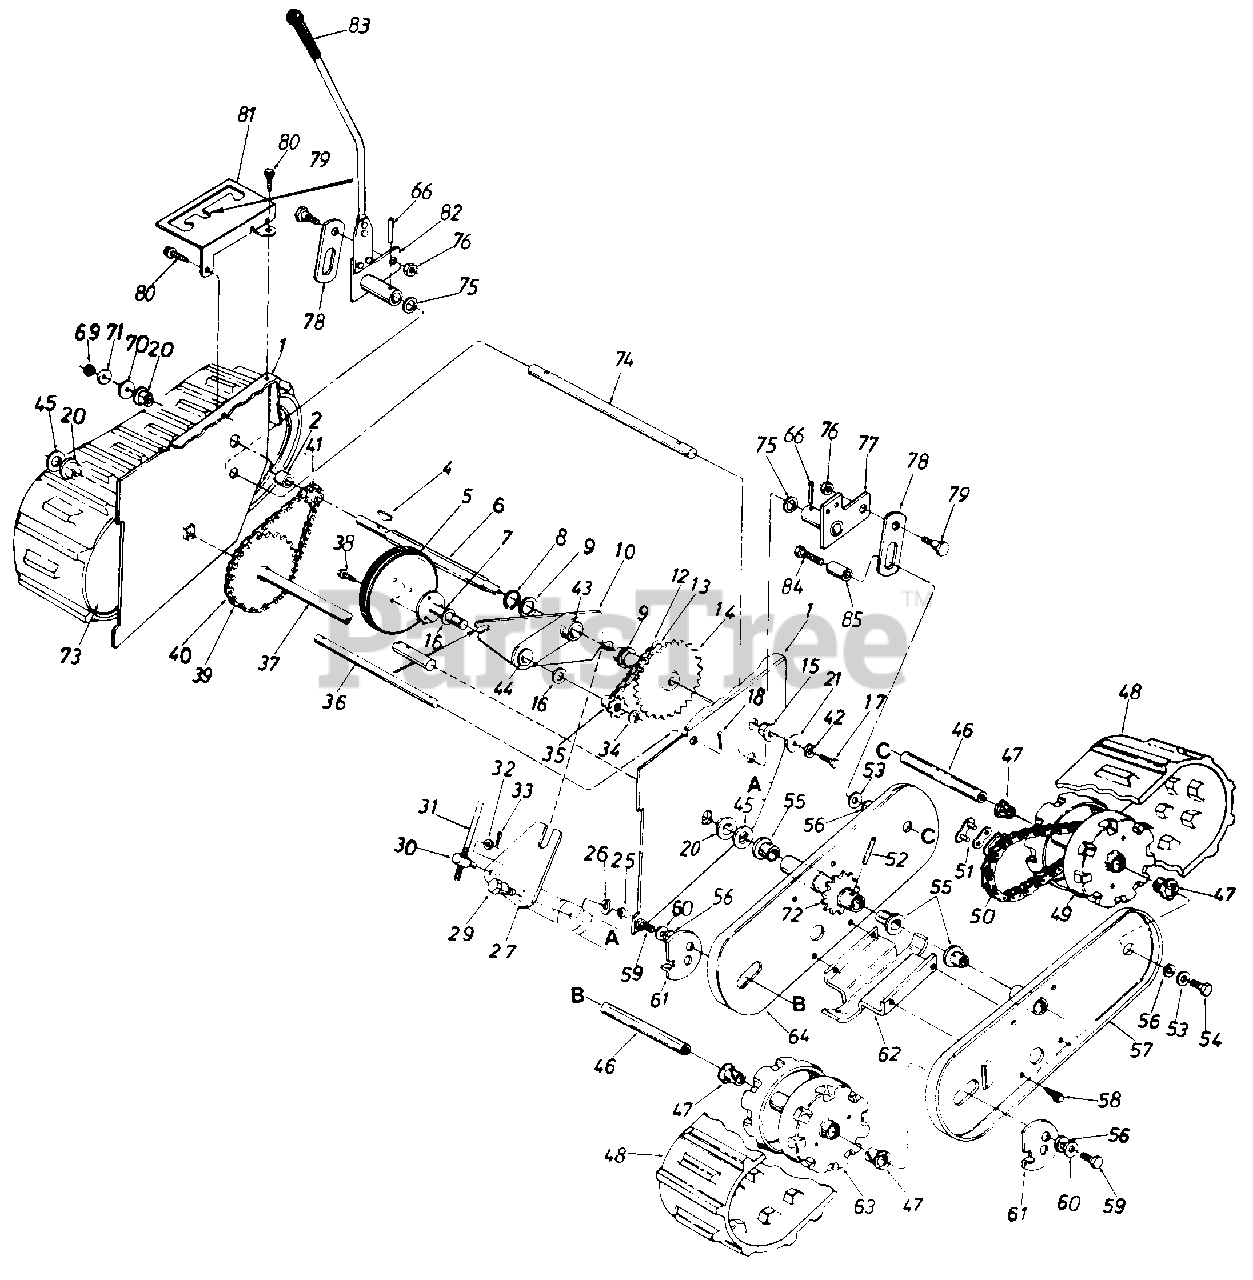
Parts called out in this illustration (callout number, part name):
1	Frame Ass'y.
2	Spacer .50" I.D. x .75" O.D. x .78" Lg.
4	#4 Hi-Pro Key 3/32 x 518" Dia.
5	Friction Wheel Ass'y.
6	Hex Shaft
7	Friction Wheel Mounting Plate Ass'y.
8	Snap Ring 1.00" Dia. Shaft
9	Fl-Wash. 1.00" x 1.63" O.D. x.03
10	Sliding Bracket Ass'y.
12	#41 Chain 1/2" Pitch x 35 Links
13	Master Link for #41 Chain
14	32 Teeth Sprocket Ass'y.
15	Hex Flange Brg. .630" I.D.
16	Fl-Wash. .62" I.D. x 1.00" O.D. x .06
17	Hex Lock Bolt 5/16-18 x .62" Lg.
18	Cotter Pin 3/32" Dia. x .75" Lg.
20	Hex Flange Brg. .751" I.D.
21	Fl-Wash. .34" I.D. x 1.12" O.D. x 125
25	Hex Jam Nut 3/8-16 Thd.
26	L-Wash. 318" I.D.
27	Shifting Linkage Bracket
29	Shld. Bolt 625" Dia. x 170" Lg.
30	Adjustment Ferrule
31	Shifting Rod 5/16" Dia. x 32.50" Lg.
32	Fl-Wash. .34" I.D. x .64" O.D. x .06
33	Cotter Pin 3/32" Dia. x .75" Lg.
34	Snap Ring .562" Dia. Shaft
35	Sprocket 7 Teeth x 50" Pitch
36	Shaft .50" Dia. x 9.50" Lg.
37	32 Teeth Wheel Shaft Ass'y.
38	Hex Wash. Hd. Self-Tap Scr. 5/16-24 x .50" Lg.
39	#420 Chain 1/2" Pitch x 39 Links
40	Master Link for #420 Chain
41	8 Teeth Center Sprocket
42	L-Wash. 5/16" I.D.
43	Plastic Bearing
44	Bronze Bearing
45	Fl-Wash. 76" I.D x 1.49 O.D.
46	Wheel Shaft 5/8 x 4.25" Lg.
47	Flange Brg. .632" I.D.
48	Snow Track 5" x 48"
49	Drive Wheel Ass'y.
50	Chain #420 x 50 Pitch x 37 Links
51	Master Link #420
52	Spring Pin Spir. 1/4" Dia. x 1.50" Lg.
53	Bell-Wash. 345" I.D. x .88" O.D.
54	Hex Bolt 5/16-24 x .62" Lg.
55	Flange Brg. .757" I.D.
56	Fl-Wash. .510" I.D. x 1.0" O.D.
57	Outer Plate Ass'y.-L.H.
58	Hex Wash. S-Tap Scr 1/4-20 X .50" Lg.
59	Hex Bolt 5/16-24 x .62" Lg.
60	Bell-Wash. .345" I.D. x .88" O.D.
61	Track Adjuster
62	Skid Shoe
63	Idler Wheel Ass'y.
64	Inner Plate Ass'y.-L.H.
66	Spring Pin 1/4" x 1.25" Lg.
69	Hex Ins. L-Nut 1/2-20 Thd.
70	Fl-Wash. .53 I.D. x 1.25 O.D. x .10
71	Bell-Wash. .50 I.D. x 1.0 O.D. x .075
72	17T Sprocket Hub Ass'y.
73	Inner Plate Ass'y.-R.H.
74	Track Lock Axle
75	Fl-Wash. 5/8 I.D. x 1" O.D.
76	Hex L-Nut 3/8-16 Thd.
77	Pivot Arm Ass'y.-L.H.
78	Slotted Link
79	Shld. Bolt .625" Dia. x .217
80	Hex Wash. AB-Tap Scr. 5/16 x .75" Lg
81	Position Selector Plate
82	Track Lock Handle Ass'y.
84	Hex Bolt 5/16-24 x 1.25" Lg. Gr. 5
85	Spacer.325" I.D.
